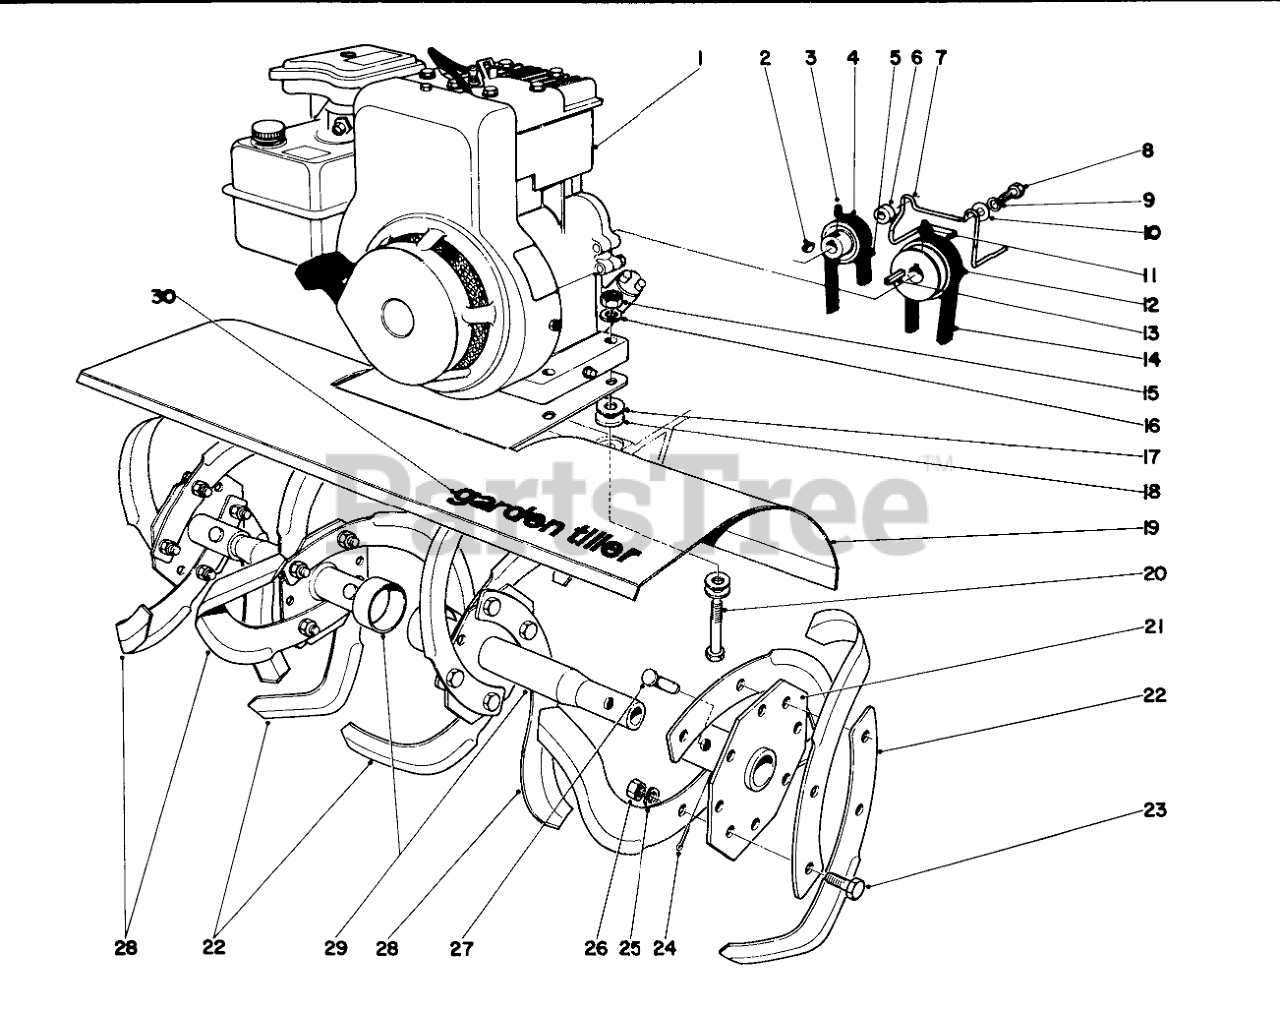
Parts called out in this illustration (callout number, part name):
1	Engine
2	KEY-WOODRUFF
3	SCREW-SET
4	Pulley
5	V-BELT
6	SPACER
7	BELT GUIDE
8	SCREW-HH
9	WASHER-LOCK
10	WASHER-FLAT
11	SCREW-SET, HSH
12	Engine Pulley
13	KEY-SQUARE
14	Belt
15	NUT-HEX
16	WASHER-LOCK
17	WASHER-FLAT
18	WASHER-FLAT
19	Shield
20	SCREW-HH
21	Axle Hub
22	RH TINE
23	SCREW-HH
24	PIN-COTTER
25	WASHER-LOCK
26	NUT-HEX
27	TINE PIN
28	LH TINE
29	Axle Hub
30	Decal
